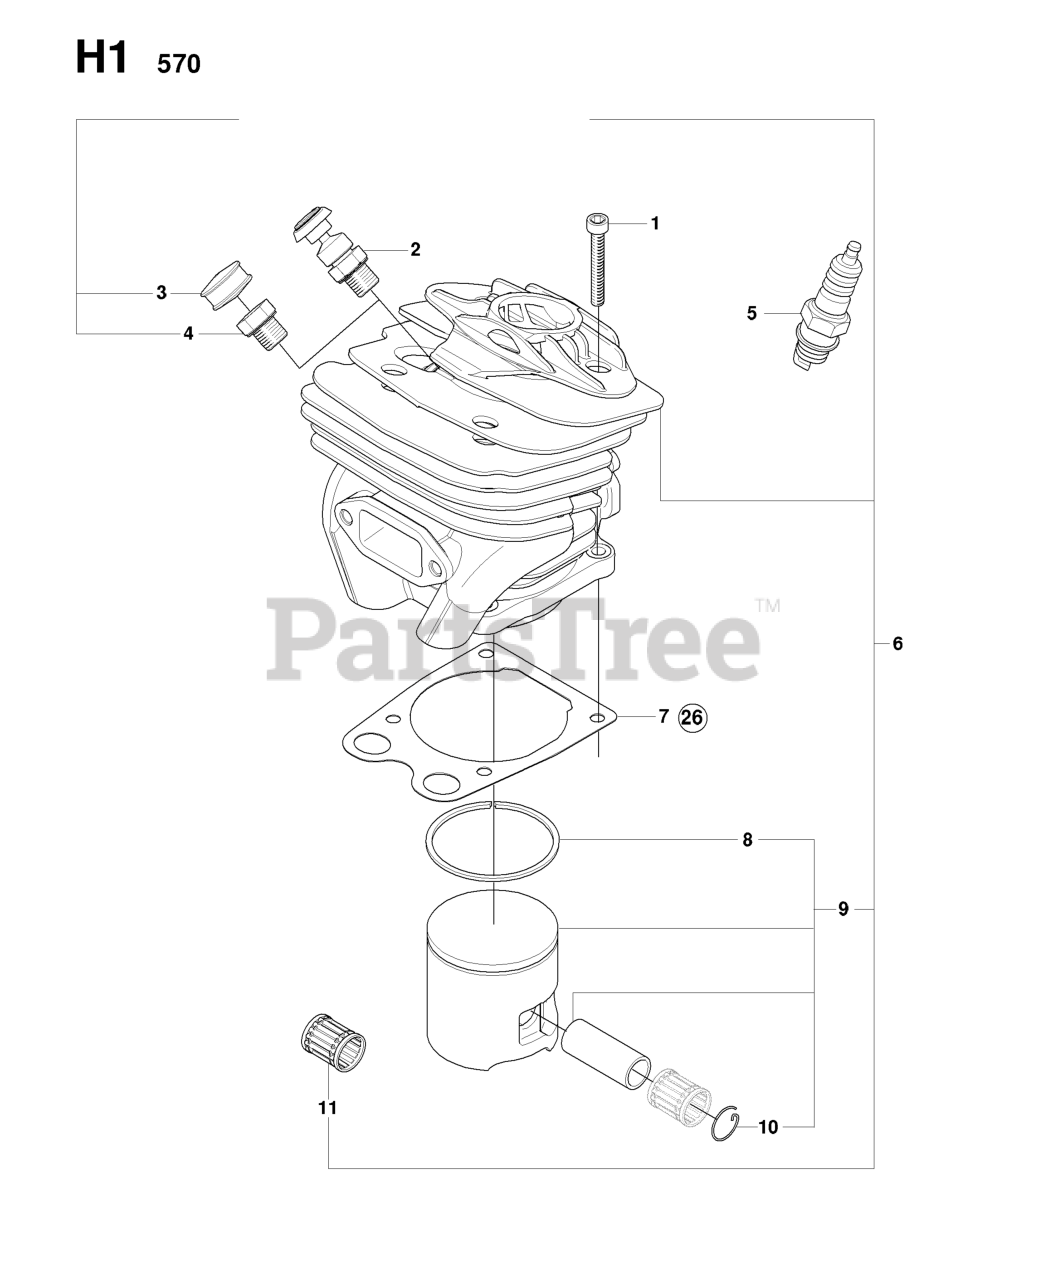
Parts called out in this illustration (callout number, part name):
1	SCREW MC6S 5X25
2	VALVE
4	CYLINDER PLUG
5	SPARK PLUG M14X1.25 NGK BPMR7A
6	%CYLINDER
8	PISTON RING
9	PISTON 49 MM
10	WRIST PIN CLIP
11	SUPPORT BUSHING
26	GASKET SET
